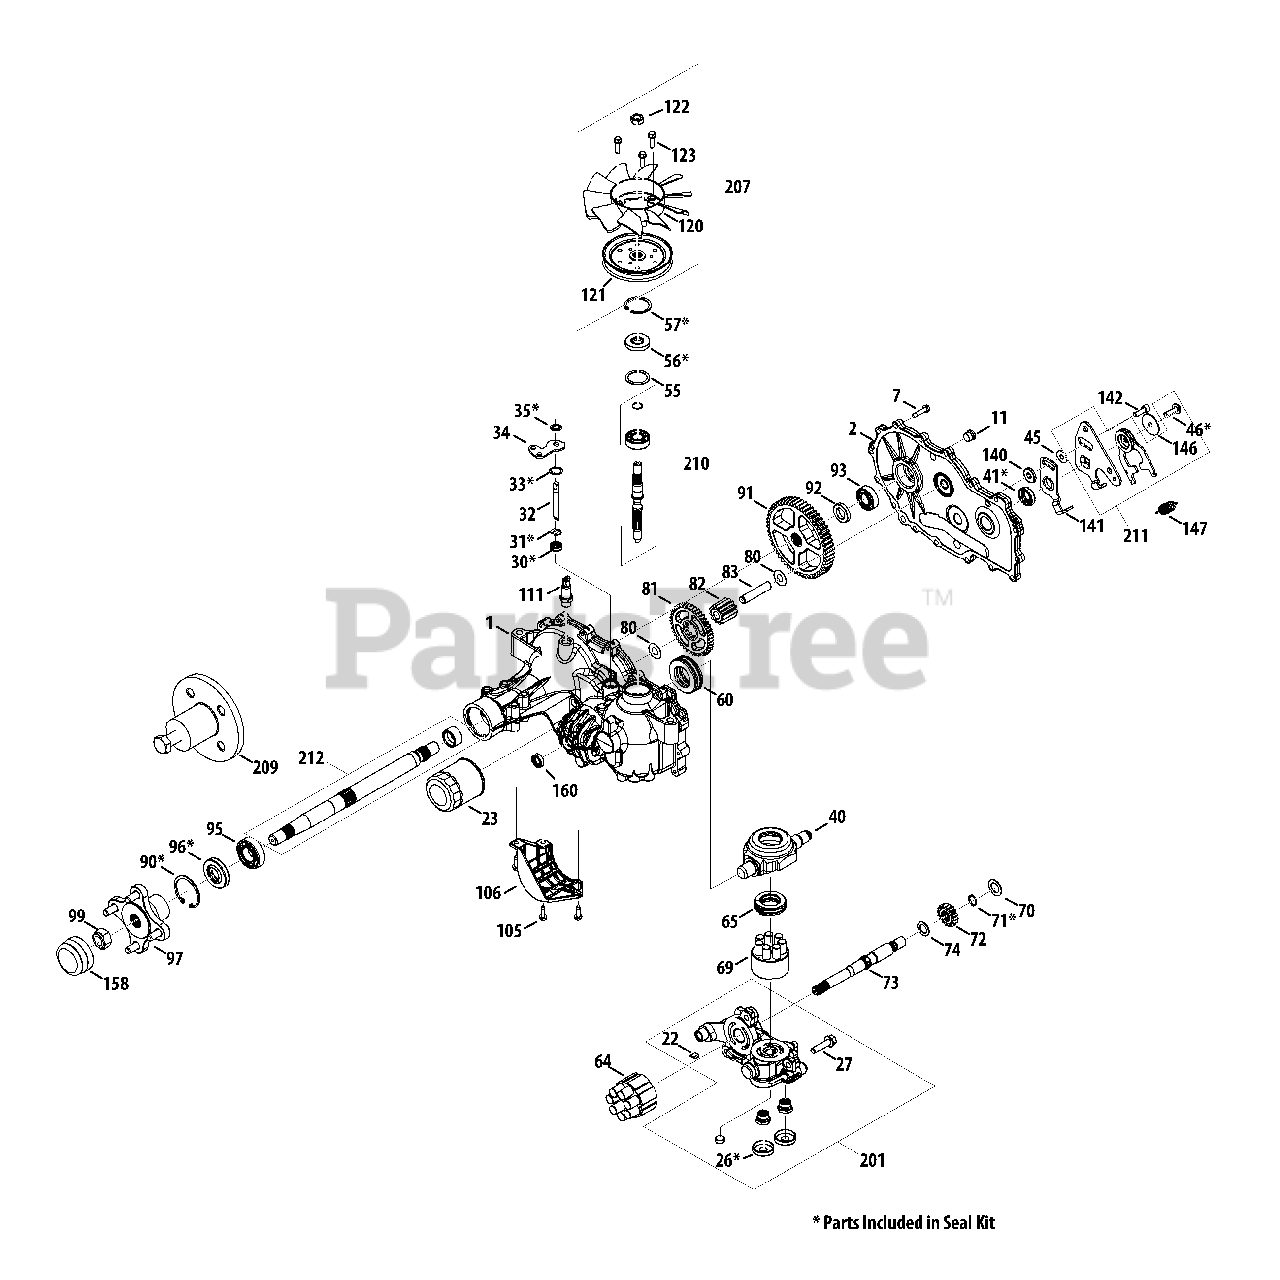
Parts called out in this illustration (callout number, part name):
1	Kit, Housing, Main, RH
2	Kit, Cover, Side, RH
7	Hex Cap Screw, 1/4-20 x 1.125
22	Plate, Bypass
23	Oil Filter
26	Seal, Plug, 1.25 x .25
27	Hex Cap Screw, 3/8-16 x 1.5
30	Seal, Lip .375 x .75 x .25
31	Ring, Ret .375 External
32	Rod, Bypass
33	Ring, Ret .75 Internal
34	Arm, Bypass
35	Ring, Retaining .375 External
40	Trunnion, Swashplate
41	Seal, Lip 12 x 32 x 7
45	Washer, .34 x .88 x .06
46	Hex Cap Screw, 5/16-24 x 1.00
55	Washer, 1.23 x 1.56 x .04
56	Seal, Lip 17 x 40 x 7
57	Ring, Retaining
60	Bearing, Thrust
64	Cylinder Block Assembly
65	Thrust Ball Bearing, 30 x 52 x 13
69	Block 7 Piston Assembly
70	Washer, .63 x 1.0 x .05
71	Retaining Ring, .625
72	Gear, 16t
73	Motor Shaft
74	Washer, .72 x 1.16 x .04
80	Washer, .5 x 1.0 x .03
81	Gear, 43t
82	Gear, 11t
83	Jack Shaft
90	Retaining Ring, 2.06 Internal
91	Gear, 54t
92	Spacer, .75 x 1.32 x .257
93	Ball Bearing, .75 x 40 x 12
95	Ball Bearing, 1.0 x 52 x 15
96	Seal, Lip 25 x 52 x 10
97	Kit, Hub, 4 Bolt
99	Nut, 3/4-16, Hex Lock
105	Hex Cap Screw, 1/4-20 x .75
106	Guard, Filter, RH
111	Fitting, 9/16-18 SAE .5 Barb
120	Fan 7", 10 Blade
121	Disc, Pulley
122	Nut, 1/2-20, Hex Jam
123	Hex Cap Screw, 1/4-20 x .875
140	Spacer, .320 x 1.005 x .179
141	Neutral Left Arm
142	Hex Cap Screw, 5/16-24
146	Washer, .343 x 1.5 x .062
147	Extension Spring, .57 x 2"
160	Seal, Lip, .625 x .875 x .25
201	Kit, Center Section, RH
207	Kit, Fan & Pulley
209	Hub Puller, 4 Bolt
210	Kit, Input Shaft
211	Kit, RTN, Bidirectional
212	Kit, Shaft, Axle
